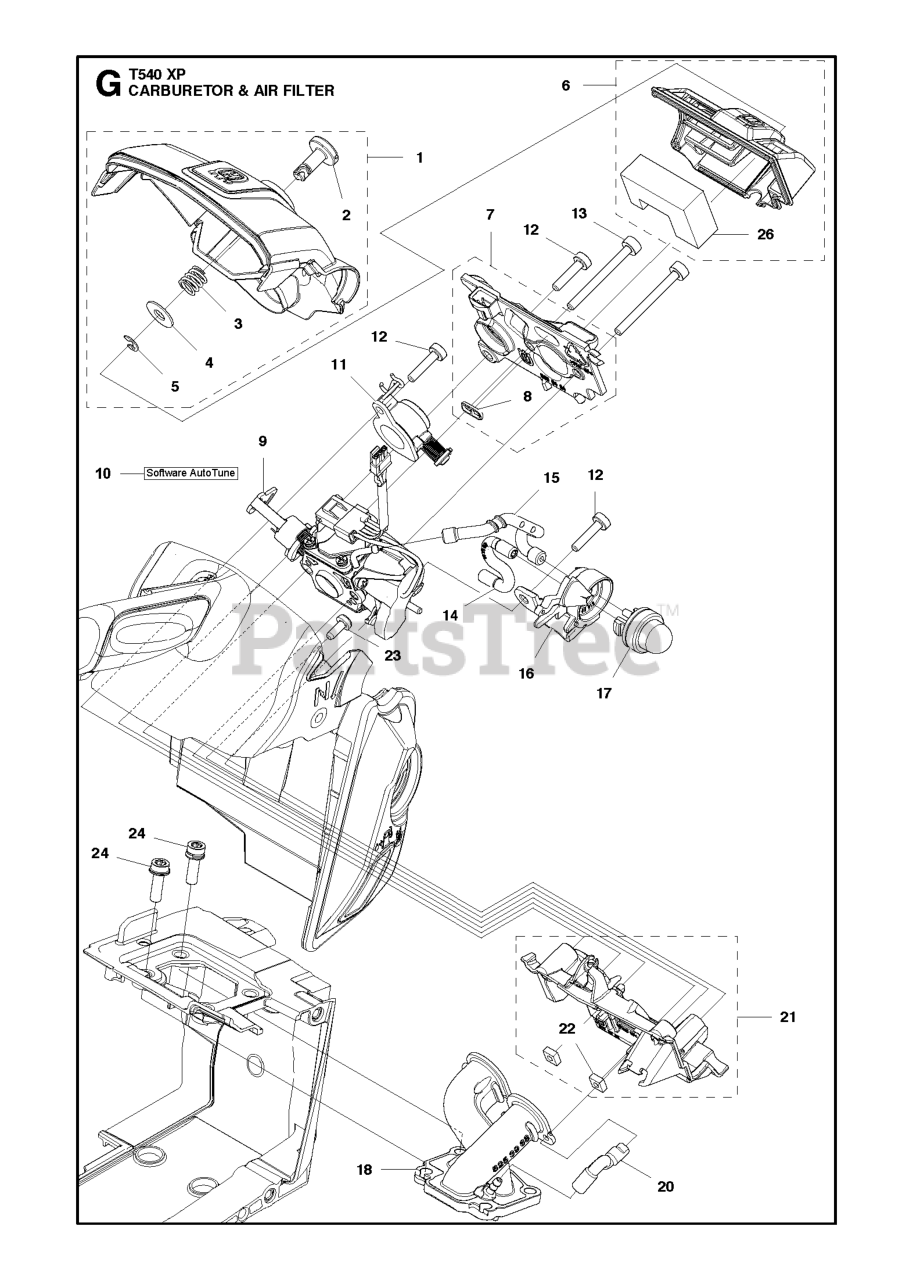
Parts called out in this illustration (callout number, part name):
1	FILTER COVER ASSY
6	AIR FILTER
6	AIR FILTER ASSY
7	RP_FILTER HOLDER ASSY
9	CARBURETTOR
11	THROTTLE ASSY
12	SCREW ITXSCT
13	SCREW ITXSCM
15	SUCTION HOSE
16	CHOKE CONTROL ASSY
17	AIR PURGE BUBBLE
18	RP_INLET PIPE ASSY
20	HOSE
21	CARBURETTOR BRACKET
22	NUT SQUARE
23	SCREW CITXPANT
24	RP_SCREW ITXSCM
26	FOAMING FILTER
